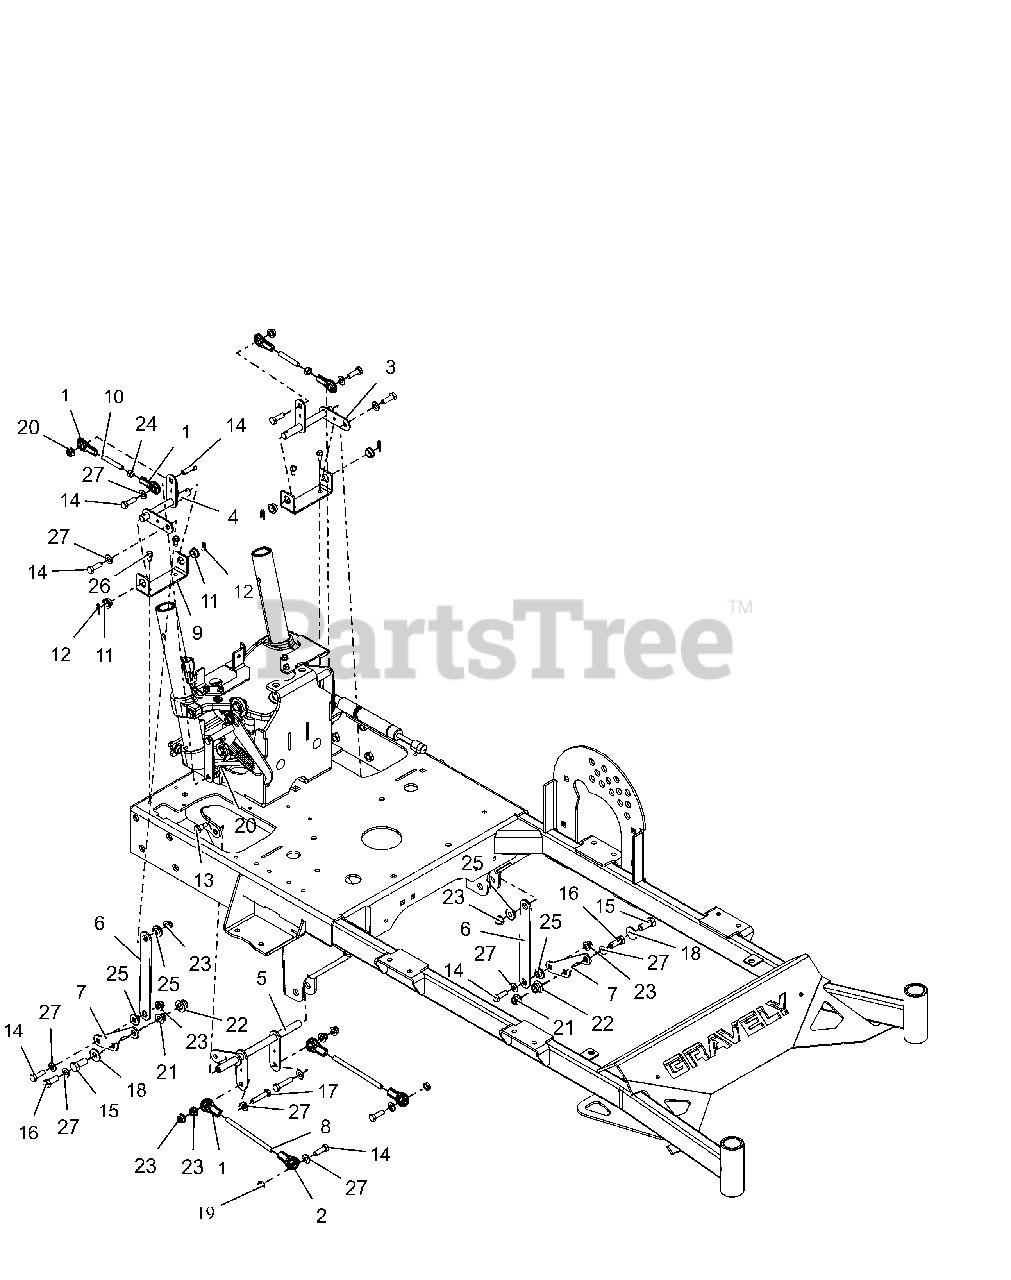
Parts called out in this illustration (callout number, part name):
1	ALIGNABALL, 5/16 RH THREAD
2	ALIGNABALL, 5/16 LH THREAD
3	WLDMT, 36" LH LOWER STEERING SHAFT
4	WLDMT, 36" RH LOWER STEERING SHAFT
5	WLDMT, BRAKE SHAFT
6	LINK, VERT STEERING (BLACK)
7	LINK, TRANSAXLE STEERING (BLACK)
8	ROD, STEERING
9	BRKT, 36" LOWER STEERING MTG (BLACK)
10	LINKAGE, STEERING
11	BSHG,FLANGE .500X.625X.270X.75
12	CLIP, SPRING
13	BOLT, SHLDR-.375X.375X.25-20
14	@BLT-HEX .31-18X1.00 GR5 YWZC
15	@BLT-HEX .44-14X1.00 GR5 YWZC
16	@BLT-HEX .38-16X1.00 GR5 YWZC
17	@BLT-HEX .31-18X1.50 GR5 YWZC
18	WSHR,FLT .438X1.00X.083 ZCC
19	@NUT-LK-CTR-JAM .31-18 YWZC
20	@NUT-LK-CTR-FLG .31-18 YZ GR F
21	@NUT-LK-NYL-FLG .38-16 YWZC
22	@NUT-LK-NYL-FLG .44-14 YWZC
23	@NUT-LK-NYL-FLG .31-18 YWZC
24	NUT-HEX .312-24 YWZC
25	BSHG-FLG .32X.500X.344X.880
26	SCR-TAP .25-20X.50 HWH TR YWZ
27	@WSHR-FL-STL.344X.688X.065YWZC
